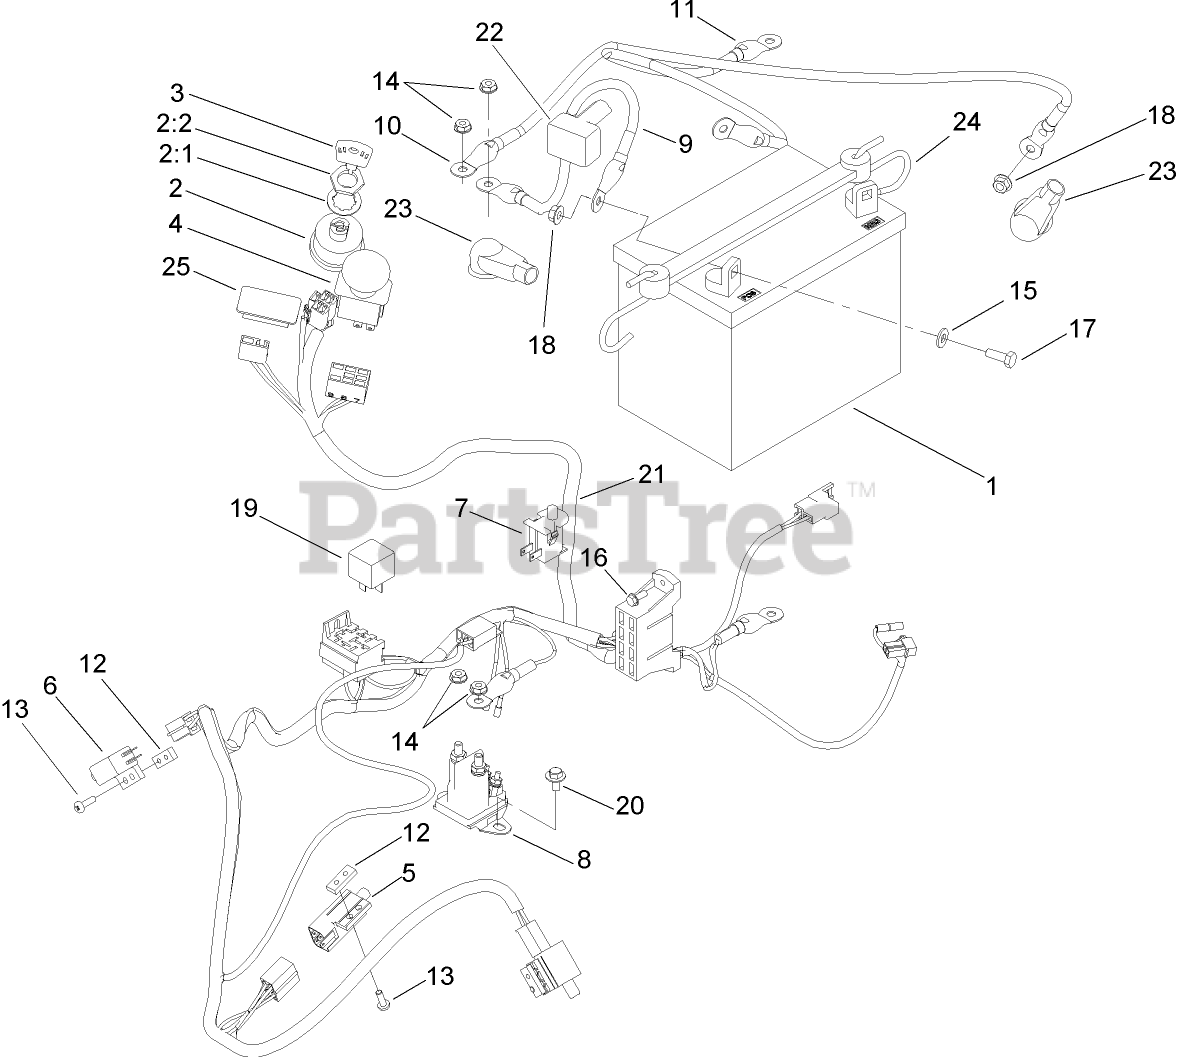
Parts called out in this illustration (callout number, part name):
2:1	WASHER-LOCK
2:2	NUT-HH
3	KEY-IGNITION
4	SWITCH-PTO,ON-ON-NONE
7	SWITCH-BAIL
8	SOLENOID-STARTER
9	WIRE ASM
10	CABLE-BATTERY, RED
11	CABLE
12	PLATE-TAPPED
13	SCREW-PPHTF
14	NUT-KEPS
15	WASHER-FLAT
16	SCREW-TAPTITE
17	SCREW-HH
18	NUT-HF
19	RELAY
20	SCREW-HHFTF
21	HARNESS-WIRE
22	BOOT-TERMINAL
23	BOOT-INSULATOR, TERMINAL
24	HOLDDOWN-BATTERY
25	PLUG-HOLE
